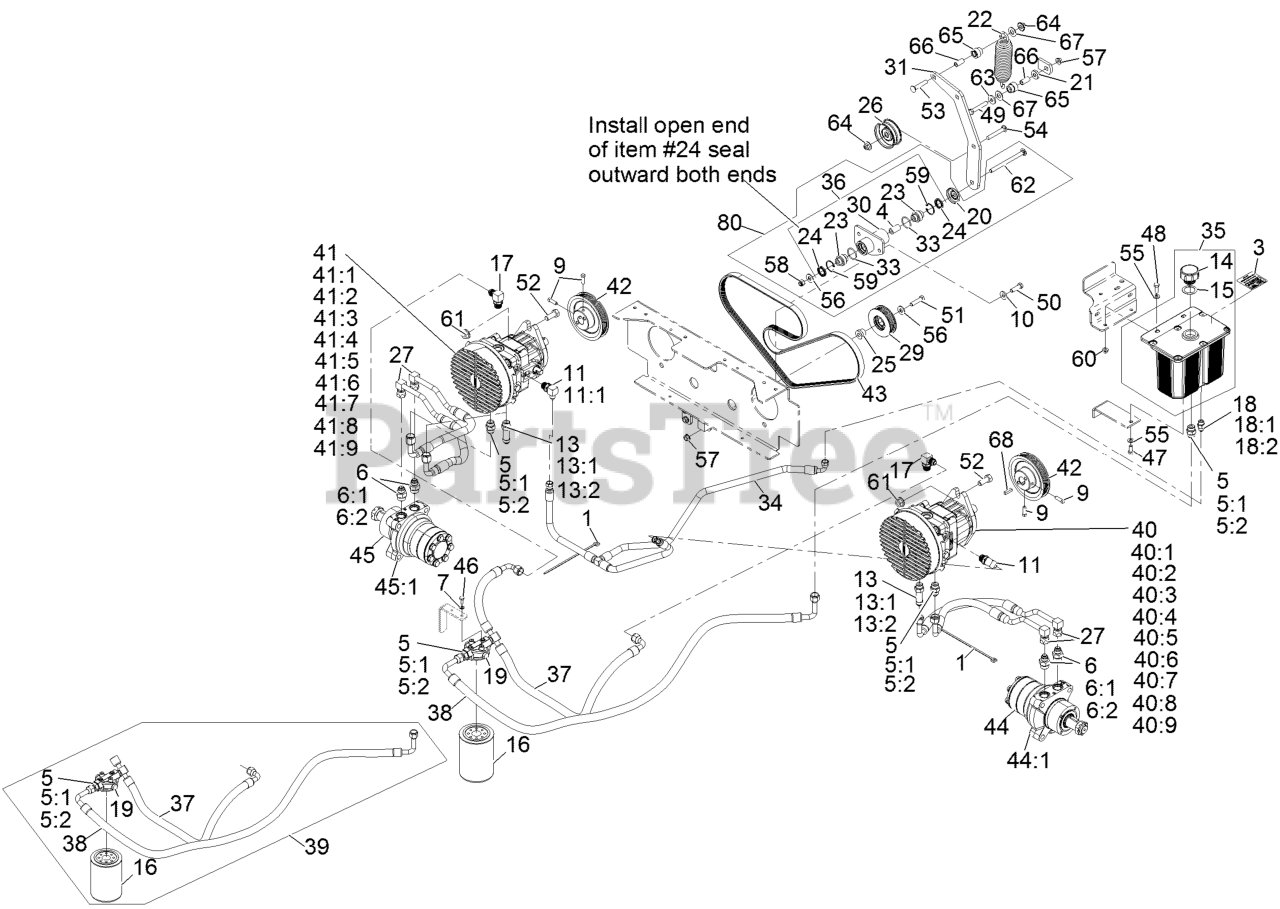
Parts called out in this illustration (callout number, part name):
1	TIE-PLASTIC
3	DECAL-HYDRAULIC TANK
5	FITTING-STRAIGHT
6	FITTING-STRAIGHT
7	WASHER-LOCK
9	SCREW-SET
10	WASHER-BELLEVILLE
11	FITTING-ELBOW, 90 DEG
13	ADAPTER-STR, LONG
14	Cap-Reservoir, HYD
15	GASKET-CAP
16	FILTER,XP HYD 25 MICRON
17	FITTING-90 DEG
18	FITTING-STRAIGHT
19	HEAD-FILTER
20	GUARD-TOP
21	SPACER-BRACKET, GUIDE
23	BEARING-SPHERICAL
24	SEAL-LIP, SINGLE
25	SPACER,LOWER FRAME IDLER
26	IDLER,FLANGED
27	HYD HOSE ASM
29	ASM,LOWER FRAME IDLER
31	ARM,PUMP IDLER
34	ASM,CASE DRAIN HOSE
36	Asm, Pump Idler
37	ASM, HOSE-PUMP INLET
38	ASM, HOSE-FILTER INLET
39	ASM, Filter HD. W/ Hoses
40	PUMP, LH
40:2	KIT, INPUT SHAFT
40:3	THRUST BEARING KIT
40:5	PLATE-VALVE
40:6	FAN-7",21CC PW PUMP
40:7	GUARD-FAN, PUMP
40:9	SHOCK VALVE KIT
41	PUMP, RH
41:2	KIT, INPUT SHAFT
41:3	THRUST BEARING KIT
41:5	PLATE-VALVE
41:6	FAN-7",21CC PW PUMP
41:7	GUARD-FAN, PUMP
41:9	SHOCK VALVE KIT
42	SHEAVE,5K 5.0" PD POLY-V
43	BELT, 5K 68.8
44	HYD MOTOR ASM (CCW)
45	HYD MOTOR ASM (CW)
46	SCREW-HH
47	SCREW-HH
48	SCREW-HH
49	SCREW-HH
50	SCREW-HH
51	SCREW-HH
52	SCREW-HH
53	SCREW-HH
54	SCREW-CARR
55	WASHER-PLAIN
56	WASHER-FLAT
57	NUT-HHF, WHIZ
58	NUT-LOCK, NI
59	RING-SNAP
61	NUT-HHF
62	BOLT CARR 3/8-16X5
63	WASHER
64	Nut-Nyloc 3/8-16 Flg
65	BUSHING,PLASTIC
67	WASHER-TEFLON
80	KIT,PUMP IDLER
